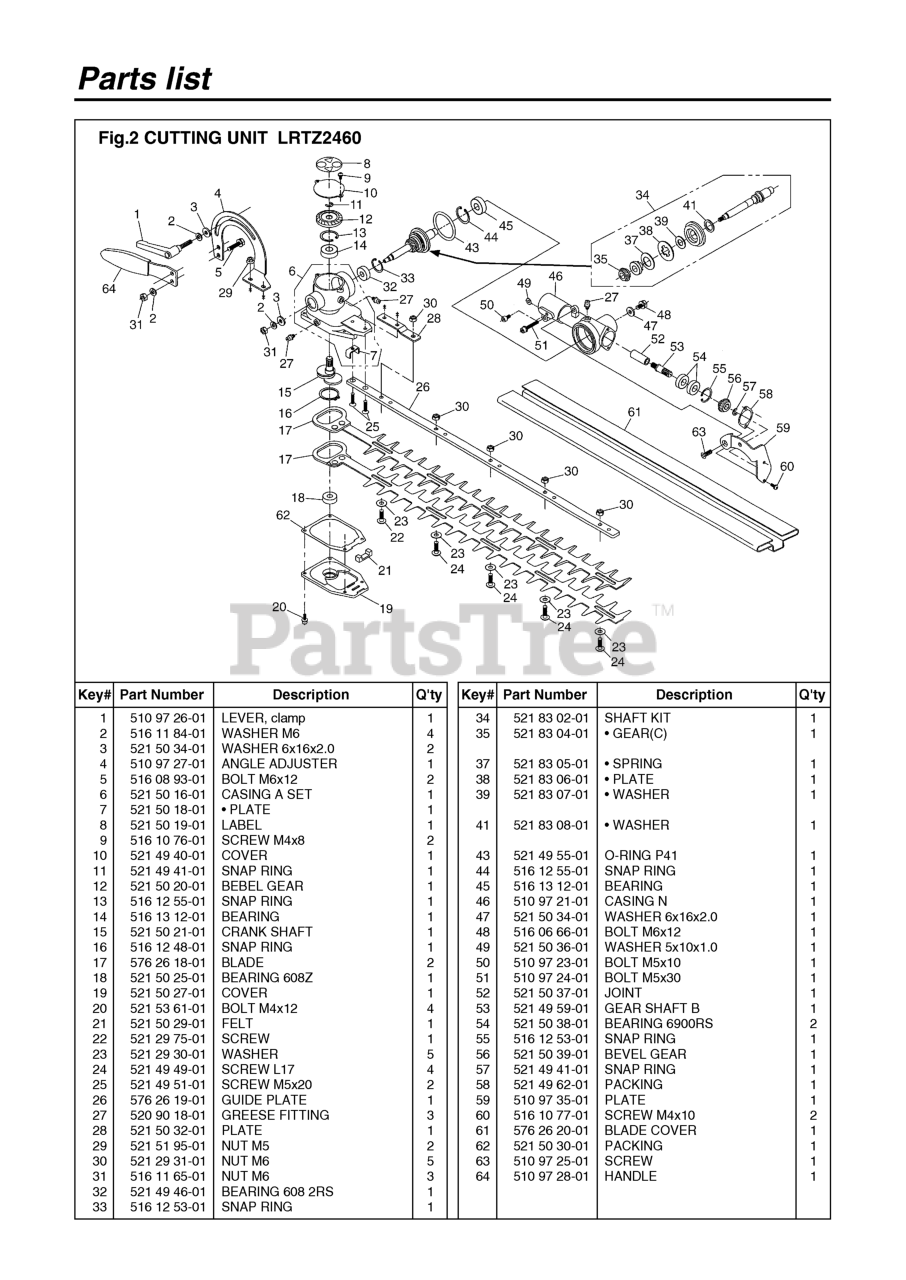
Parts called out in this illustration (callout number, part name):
1	CLAMP LEVER
2	WASHER, M6 x 15
3	WASHER,6x15x2.0(
4	ANGLE ADJUSTER
5	BOLT
6	CASE (A) SET RPL
7	PLATE
8	LABEL
9	SCREW, M4 x 8
10	COVER
11	RING, SNAP
12	GEAR, BEVEL
13	RING,SNAP M26x1.
15	CRANKSHAFT
16	RING, SNAP, M28
18	BEARING
19	COVER
21	FELT
22	SCREW(R3873,3884
23	WASHER RPL 38731
24	SCREW
25	SCREW, M5 x 20
26	GUIDE PLATE
27	FITTING, GREASE
28	PLATE (RPLS 6780
30	NUT, M6
31	NUT, M6 x 5 (RPL
32	BEARING
33	RING, SNAP, M22
34	KIT,SHAFT(R67821
35	GEAR (C)
37	WASHER, SPRING
43	O-RING
44	RING,SNAP M26x1.
46	CASE (B)
47	WASHER,6x15x2.0(
48	BOLT M6x12 (RPLS
50	BOLT M5X10
51	BOLT M5X30
52	JOINT (RPLS T307
53	SHAFT, GEAR
54	BEARING
55	RING, SNAP, M22
56	GEAR, BEVEL
57	RING, SNAP
58	PACKING
60	SCREW, M4 x 10 (
61	BLADE COVER
62	GASKET
